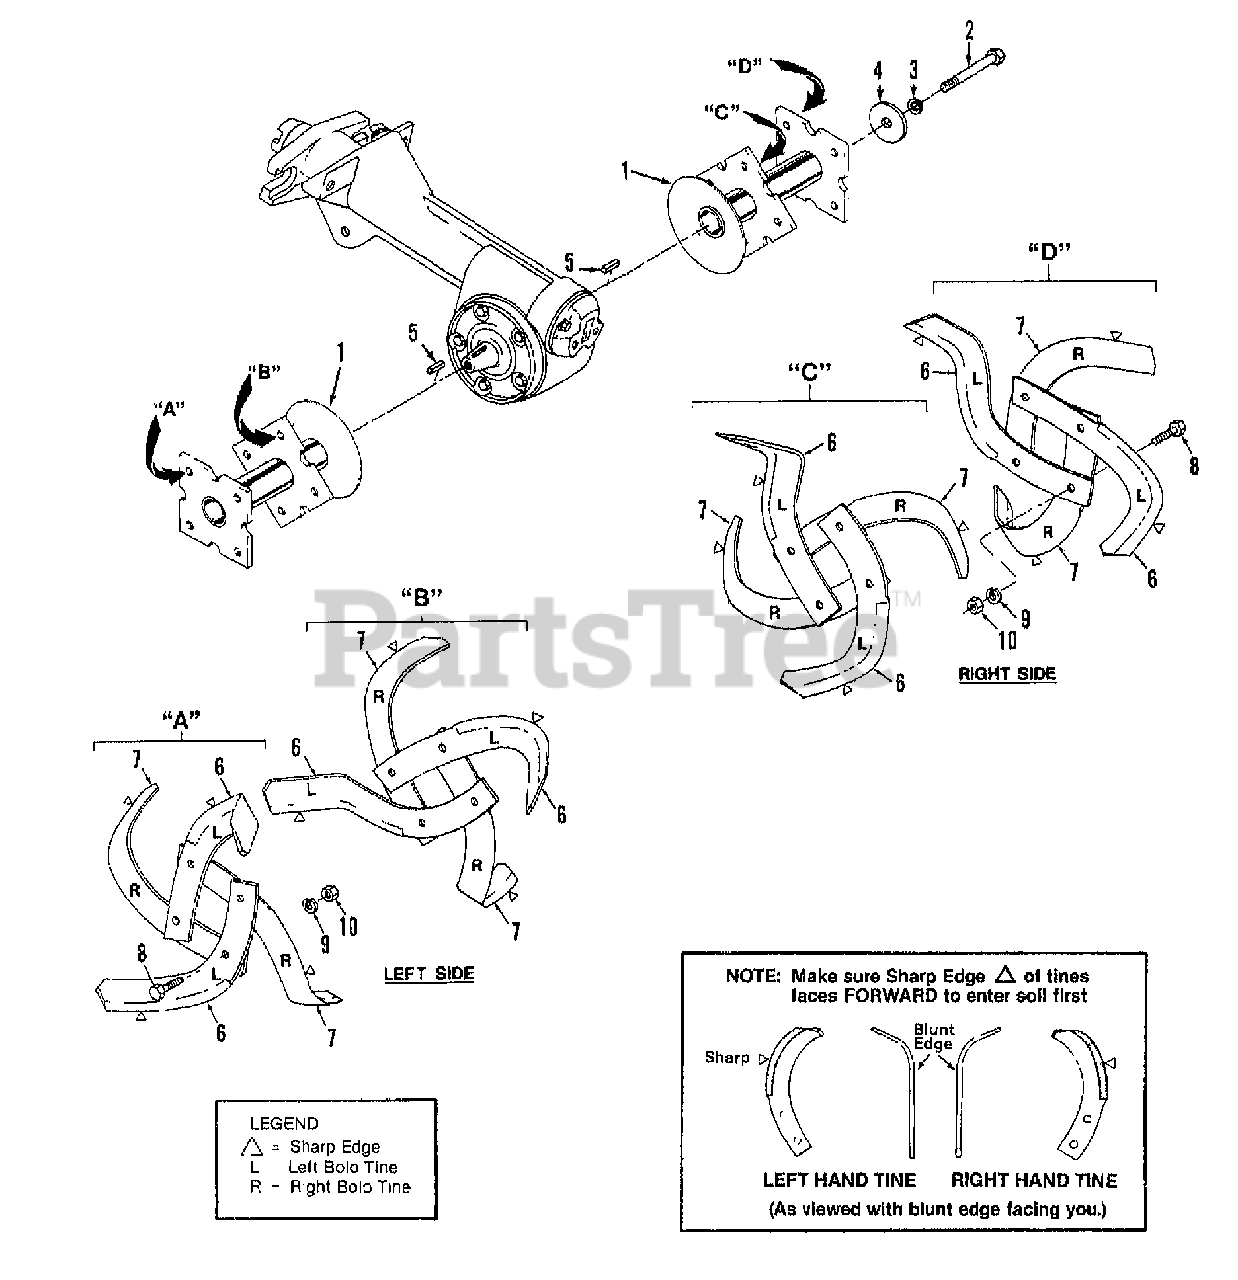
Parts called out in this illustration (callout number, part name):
1	HOLDER-TINE RED
2	SCR-HH 1/2-20X4.75 GR5
3	WASHER-LK .5
4	WASHER-1.5X.531X.187
5	KEY-.188 SQX1.0
6	TINE-BOLO LT W/HDW
7	TINE-BOLO RT W/HDW
8	SCR-HH 3/8-16X1.0 G5 ZP
9	WASHER-LK .375 @ DEPL
10	NUT-HEX 3/8-16 ZP
